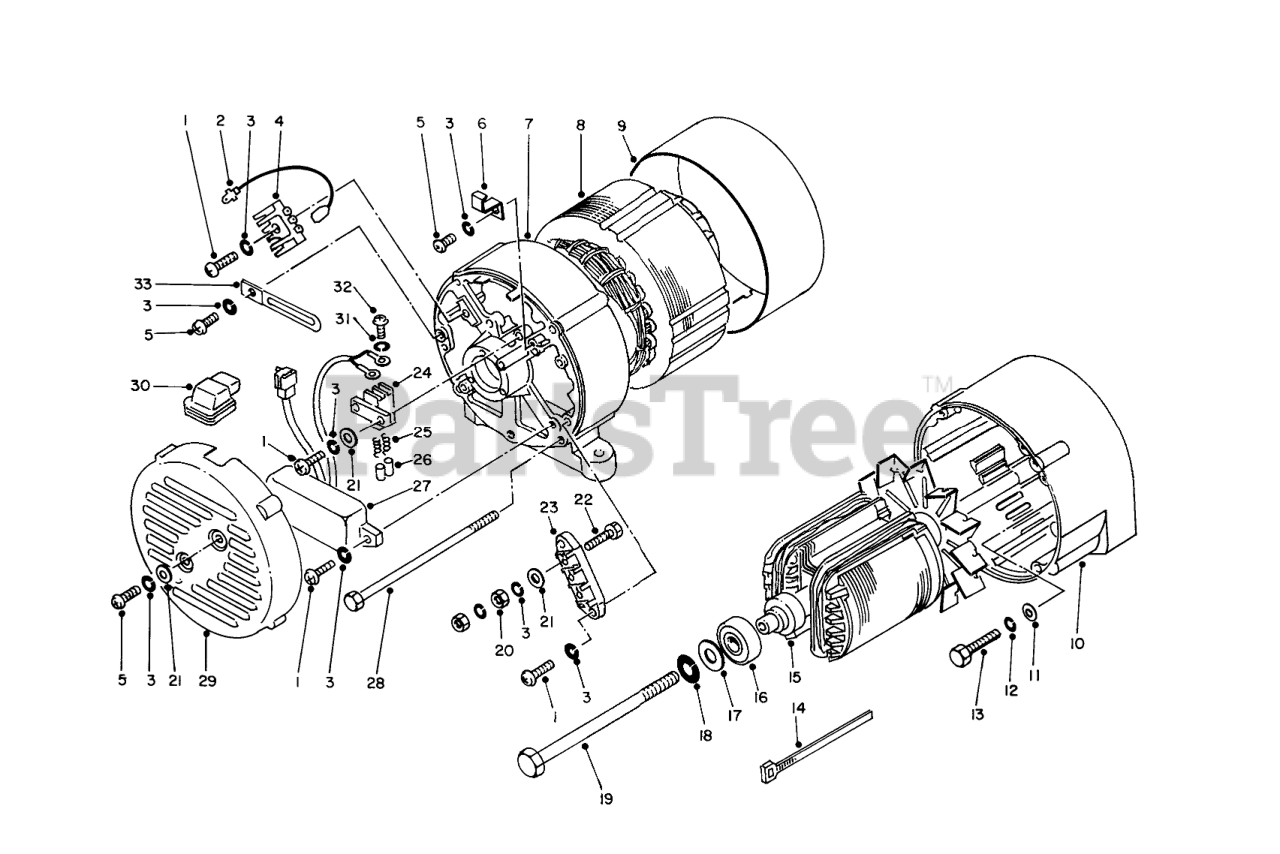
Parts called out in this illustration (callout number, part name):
1	Screw
2	Fusible Link
3	Washer
4	Rectifier
5	SCREW
6	Clamp
7	Housing-Rear
8	Stator (120V +120V/240V)
9	Cover-Stator Core
10	Housing-Front
11	Washer
12	WASHER-LOCK
14	Clamp
15	Rotor
16	Bearing
17	WASHER
18	Washer-Lock
19	Bolt-Rotor
21	WASHER
23	Terminal Assembly (Incl. Ref. #3 & 20-22)
24	Brush Assembly (Incl. Ref. #25, 26 & 31-32)
25	Spring
26	BRUSH
27	REGULATOR
28	Bolt-Stator
29	Cover-Rear
30	Grommet
31	Lockwasher
33	Clamp
